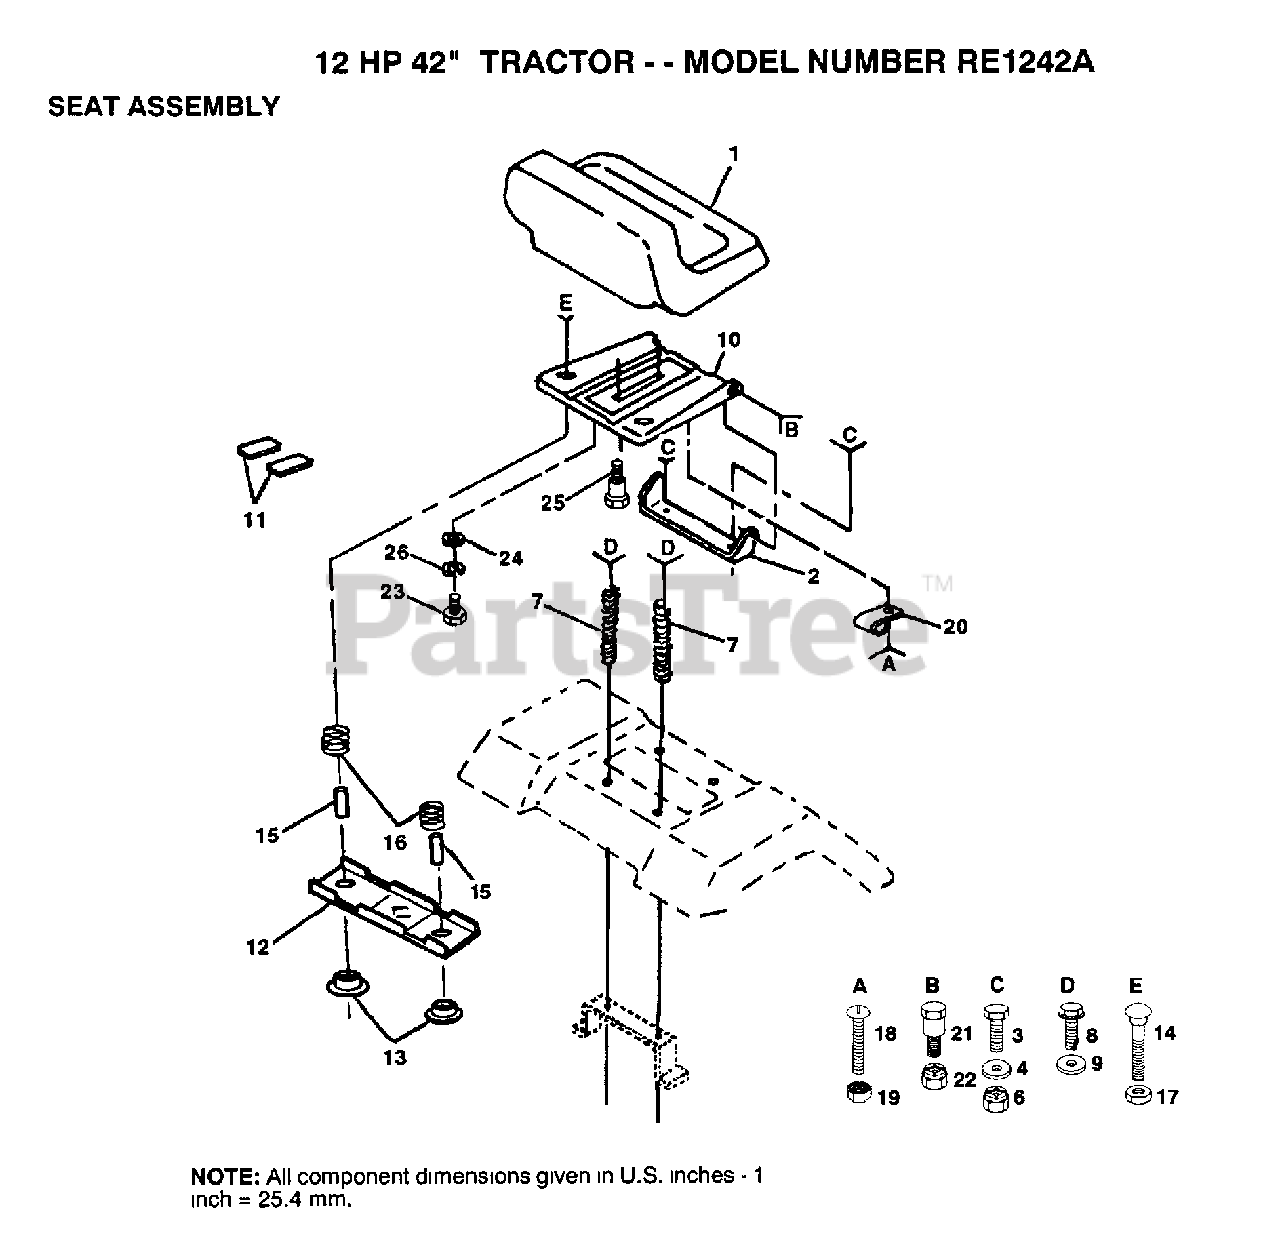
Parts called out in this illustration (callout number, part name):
4	WASHER
7	SPRING COMPRESSIO
8	SCREW GTV
9	WASHER
11	STRIP FORM
12	BRKT SWITCH
13	BUSHING
15	SPACER SPLIT
16	SPRING
19	"NUT,KEPS"
23	BOLT
24	WASHER
25	"BOLT,SHOULDER"
26	LOCKWASHER
